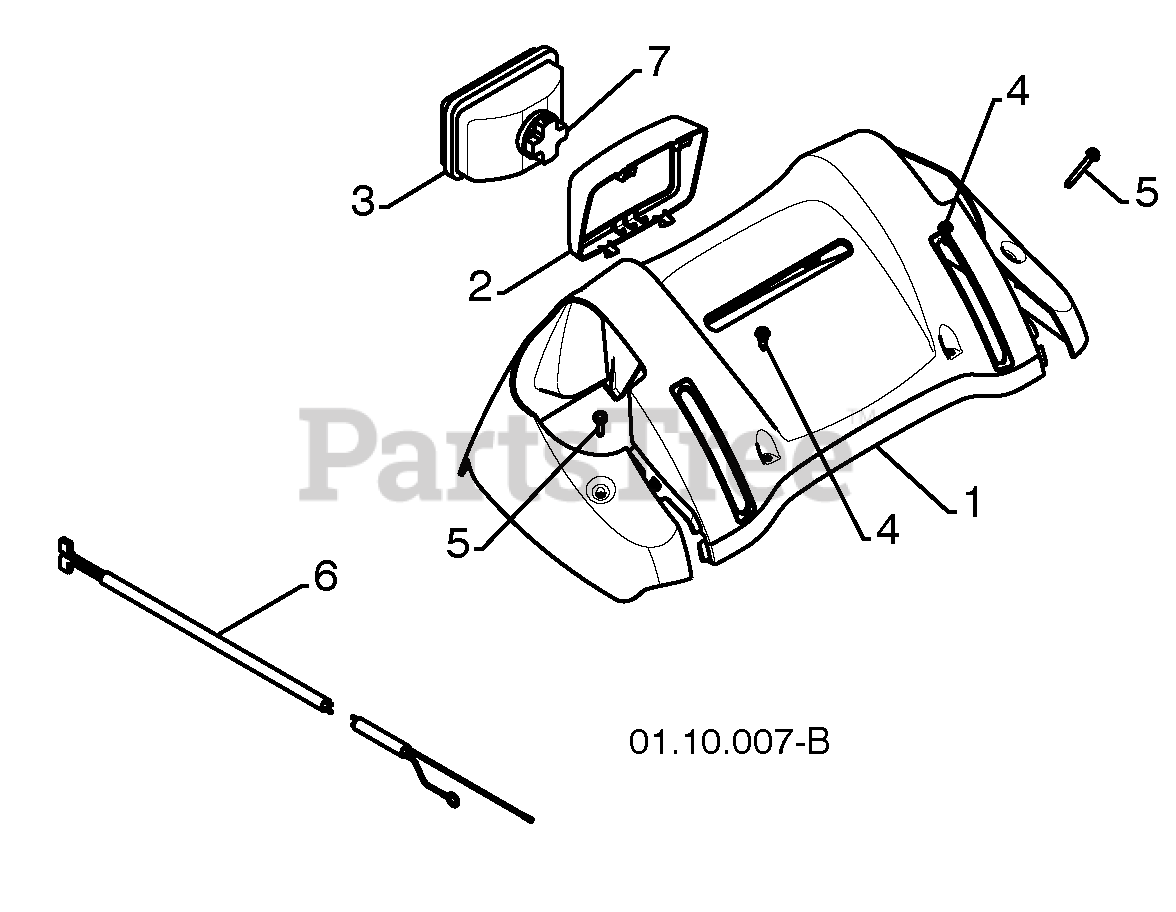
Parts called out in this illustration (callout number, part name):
1	CONSOLE PANEL
2	HEADLIGHT BEZEL
3	FLOOD HEADLIGHT
4	SHOULDER SCREW 10-24 X .625
5	SCREW 10-24 X 1.25
6	WIRE HARNESS
7	BULB
